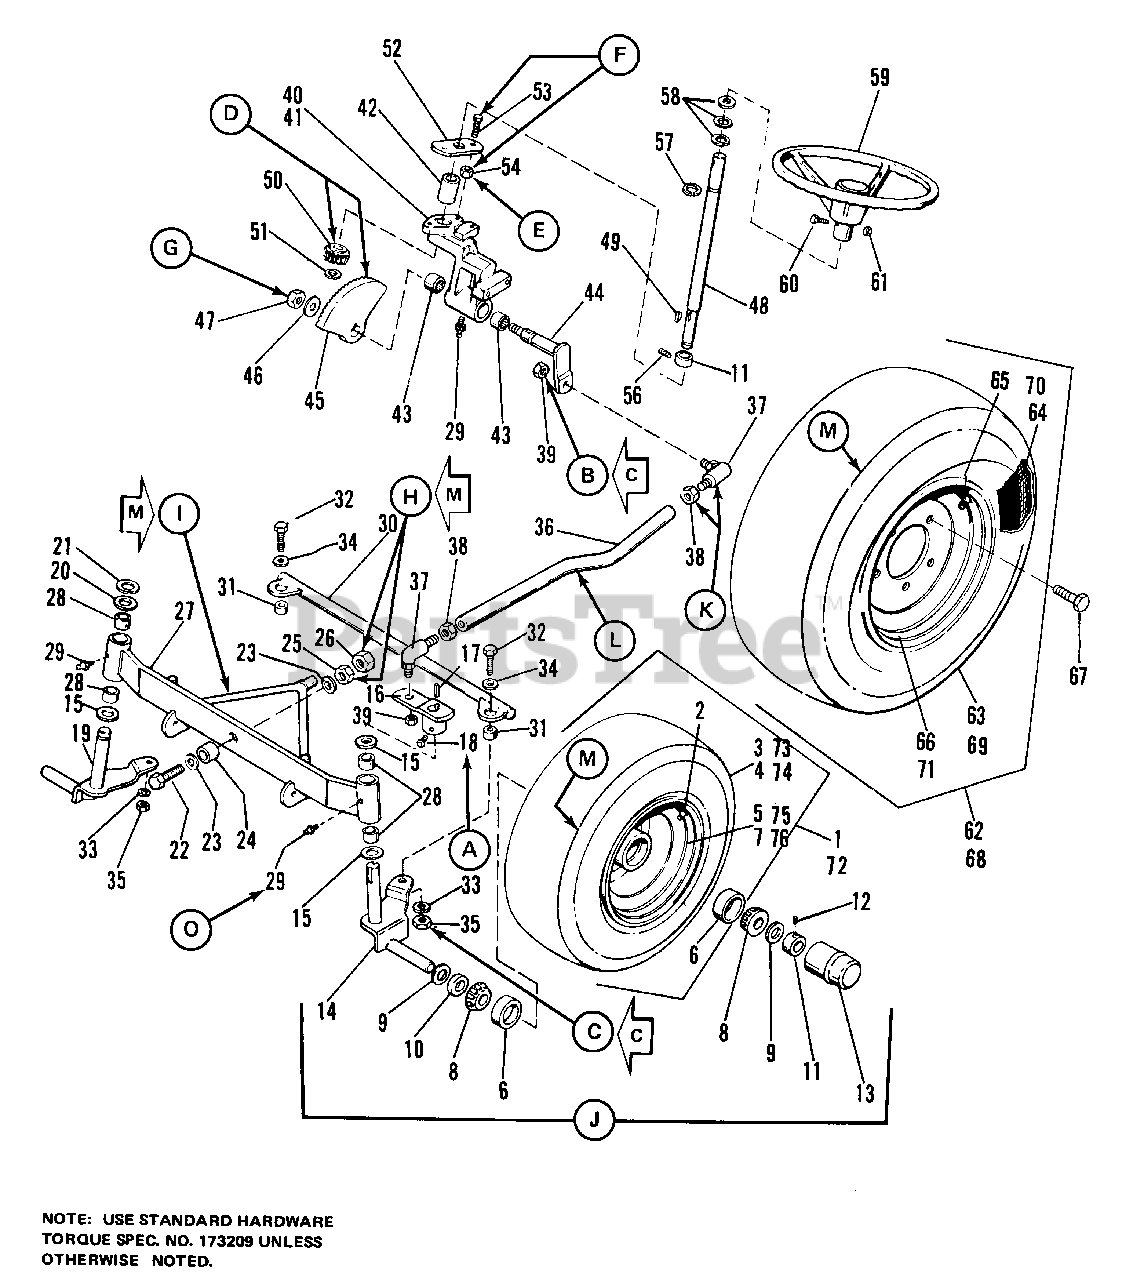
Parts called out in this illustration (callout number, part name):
1	WHEEL & TIRE ASSEMBLY (7010 Only)
2	VALVE STEM & CAP (7010 Only)
3	TIRE (7010 Only)
4	TUBE (7010 Only)
5	WHEEL ASSEMBLY (7010 Only)
6	CUP, Bearing (7010 Only)
7	WHEEL (7010 Only)
8	CONE, Bearing
11	COLLAR, Set
12	SETSCREW, Sq. Hd., Cup Pt., 5/16-18 x 5/16
13	CAP, Hub
14	SPINDLE ASSY, L.H.
16	ARM, Steering, L.H.
17	KEY, Square
18	SETSCREW, 5/16-18 x 1/2
19	SPINDLE ASSY, R.H.
21	RING, Retaining, No. 75
22	CAPSCREW, Hex Hd., 1/2-13 x 2-1/4
23	WASHER, Plain, 1/2
25	LOCKNUT, Hex, 1/2-13
26	NUT, Jam Hex, 1/2-13
27	FRONT AXLE ASSY
29	FITTING, Grease
30	TIE ROD ASSY
32	CAPSCREW, Hex Hd., 3/8-16 x 1-1/4
33	LOCKWASHER, 3/8
34	WASHER, Plain, 3/8
35	NUT, Hex, 3/8-16
36	LINK, Drag
37	JOINT, Ball
38	NUT, Jam Hex, 1/2-20
39	LOCKNUT, Hex, 1/2-20
40	STEERING HOUSING ASSEMBLY
41	HOUSING, Steering
43	BEARING, Needle
44	STEERING ARM ASSEMBLY
45	GEAR, Bevel
46	WASHER, Plain, 7/16
47	LOCKNUT, Hex, 7/16-14
48	SHAFT, Steering
49	KEY, Woodruff, No. 6, 5/32 x 5/8
50	PINION, Bevel
51	"E" RING
52	PLATE, Steering
53	CAPSCREW, Hex Hd., 3/8-16 x 1-1/4
54	LOCKNUT, 3/8-16
56	SETSCREW, Sq. Hd., 5/16-18 x 1/4
57	RING, Retaining
59	WHEEL, Steering
60	CAPSCREW, Hex Hd., 5/16-18 x 1-1/4
61	LOCKNUT, Flange, 5/16-18
62	WHEEL & TIRE ASSEMBLY
63	TIRE 23-8.50 x 12
65	STEM & VALVE CAP
66	WHEEL, Drive
68	WHEEL & TIRE ASSEMBLY 23-10.50 x 12 (7016 Only)
69	TIRE (7016 Only)
70	TUBE (7016 Only)
71	WHEEL DRIVE (7016 Only)
72	WHEEL & TIRE ASSY
75	WHEEL ASSY
76	WHEEL
